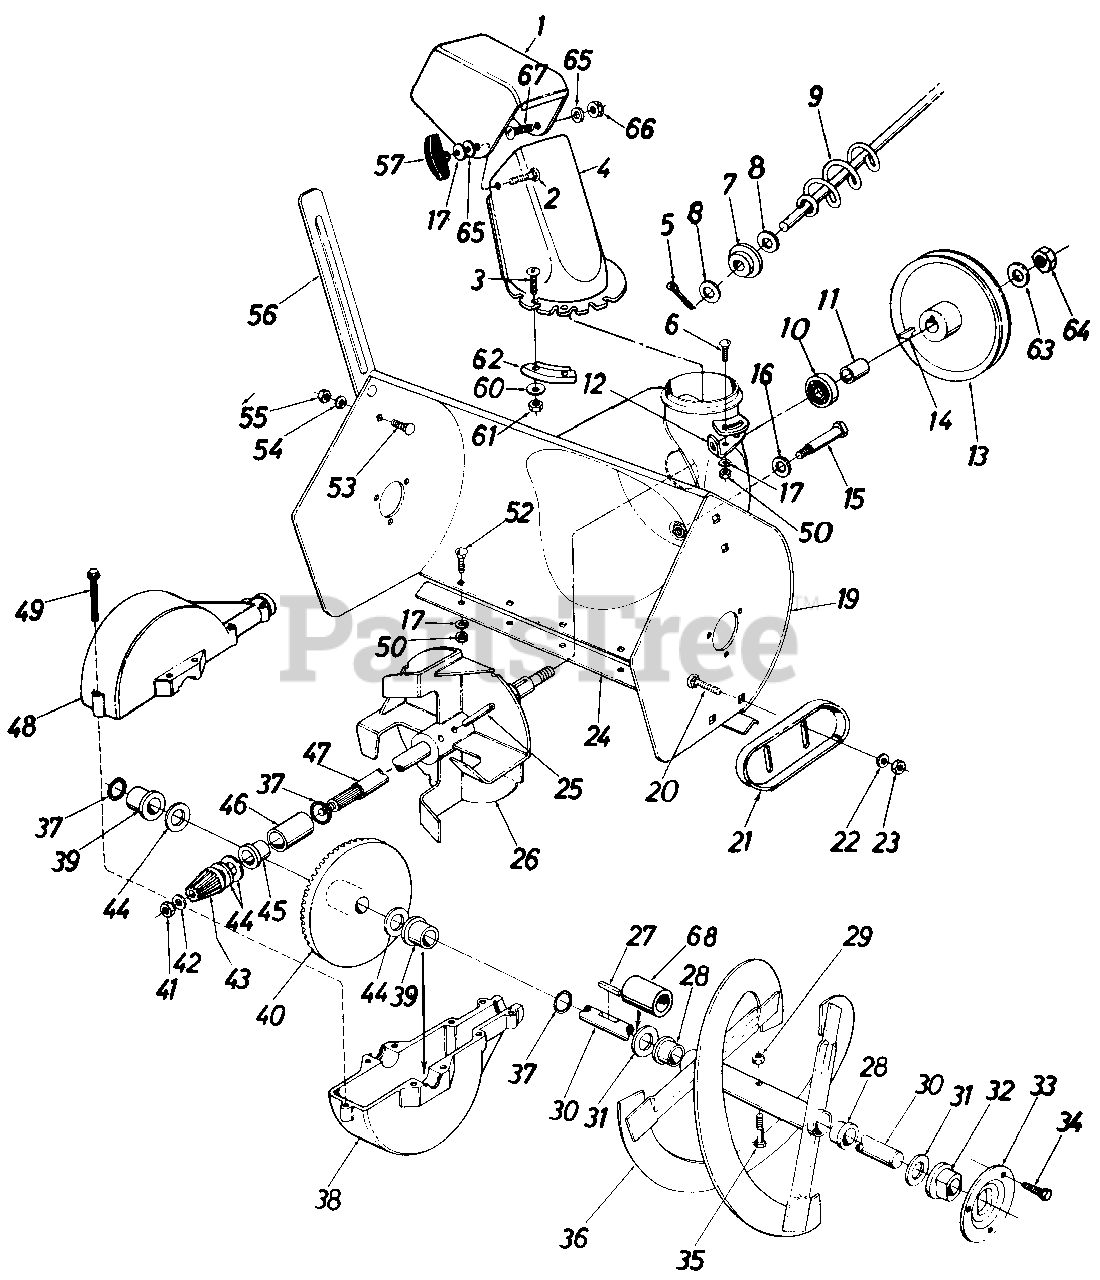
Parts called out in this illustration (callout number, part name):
1	Upper Chute
2	Carriage Bolt 5/16-18 x 1.0
3	Truss Mach. Scr. 1/4-20 x 75
4	Lower Chute
5	Cotter Pin
6	Carriage Bolt 5/16-18 x .75"
7	Bushing
8	Fl-Wash. .385 I.D. x .62" O.D.
9	Chute Crank Ass'y.
10	Ball Brg. .62" l.D. x 1.38" O.D.
11	Spacer .63" I.D. x .88" O.D. x .900" Lg.
12	Chute Crank Brkt.
13	/2" "V"-Pulley .625" I.D. x 7.50" O.D.
13	5/8" "V"-Pulley .625" l.D. x 7.50" O.D.
14	#61 Hi-Pro Key 3/16" x 5/8" Dia
15	Shld. Bolt .50" Dia. x 2.11n
16	Bell-Wash. .40" l.D. x .88" O.D. x .06
17	Bell-Wash. .34" I.D. x .88" O.D.
19	26" Blower Housing Ass'y.
20	Carriage Bolt 3/8-16 x .62"
21	Slide Shoe
22	Bell-Wash. 3/8" l.D.
23	Hex Jam Nut 3/8-16 Thd.
24	20" Shave Plate
24	24" Shave Plate
24	26" Shave Plate
25	Spring Pin Spiral 1/4" Dia. x 1.50" Lg.
26	11" Dia. Blower Fan Ass'y.
27	Sq. Key 3/16" x 1.5" Lg.
28	Flange Brg. .75" l.D. x .88" O.D.
29	Hex Ins. L-Nut 5/16-18
30	Spiral Axle
31	Fl-Wash. .75" I.D. x 1.50" O.D. x .06
32	Flange Brg. w/Flats .755" I.D.
33	Bearing Housing
34	Hex Wash. Hd. Self-Tap Scr. 5/16-24 x .62" Lg.
35	Hex Bolt 5/16-18 x 1.50" Lg.
36	20" Spiral Ass'y.-L.H.
36	20" Spiral Ass'y.-R.H.
36	24" & 26" Spiral Ass'y.-L.H.
36	24" & 26" Spiral Ass'y.-R.H.
37	O-Ring-3/4" I.D.
38	Bevel Gear Housing-Lower Half
39	Plastic Flange Brg. .755" I.D.
40	Bevel Gear
41	Hex Cent. L-Nut 5/16-24 Thd.
42	Fl-Wash. .34" I.D. x .62" O.D. x .06
43	Pinion Gear
44	Fl-Wash. .75" I.D. x 1.25" O.D. x .06
45	Flange Brg. .755" l.D.
46	Sleeve Brg. ,755" I.D.
47	Blower Axle
48	Bevel Gear Housing-Upper Half
49	Hex Wash. Hd. Self-Tap Scr. 1/4-20 x 1.00" Lg.
50	Hex Nut 5/16-18 Thd.
52	Carriage Bolt 5/16-18 x .62
53	Carriage Bolt 5/16-18 x .62" Ly.
54	L-Wash. 5/16" I.D.
55	Hex Nut 5/16-18 Thd.
56	Drift Cutter Bar
60	Fl-Wash. 1/4" I.D.
61	Hex L-Nut 1/4-20 Thd.
62	Chute Flange Keeper
63	Fl-Wash. .64" I.D. x ,94" O.D. x .06
64	Hex Jam Nut 5/8-18 Thd.
65	Fl-Wash. .344 I.D. x 1.125 O.D.
66	Hex L-Nut 5/16-18 Thd.
67	Truss Mach. Scr. 5/16-18 x ,75" Lg.
68	Spacer
